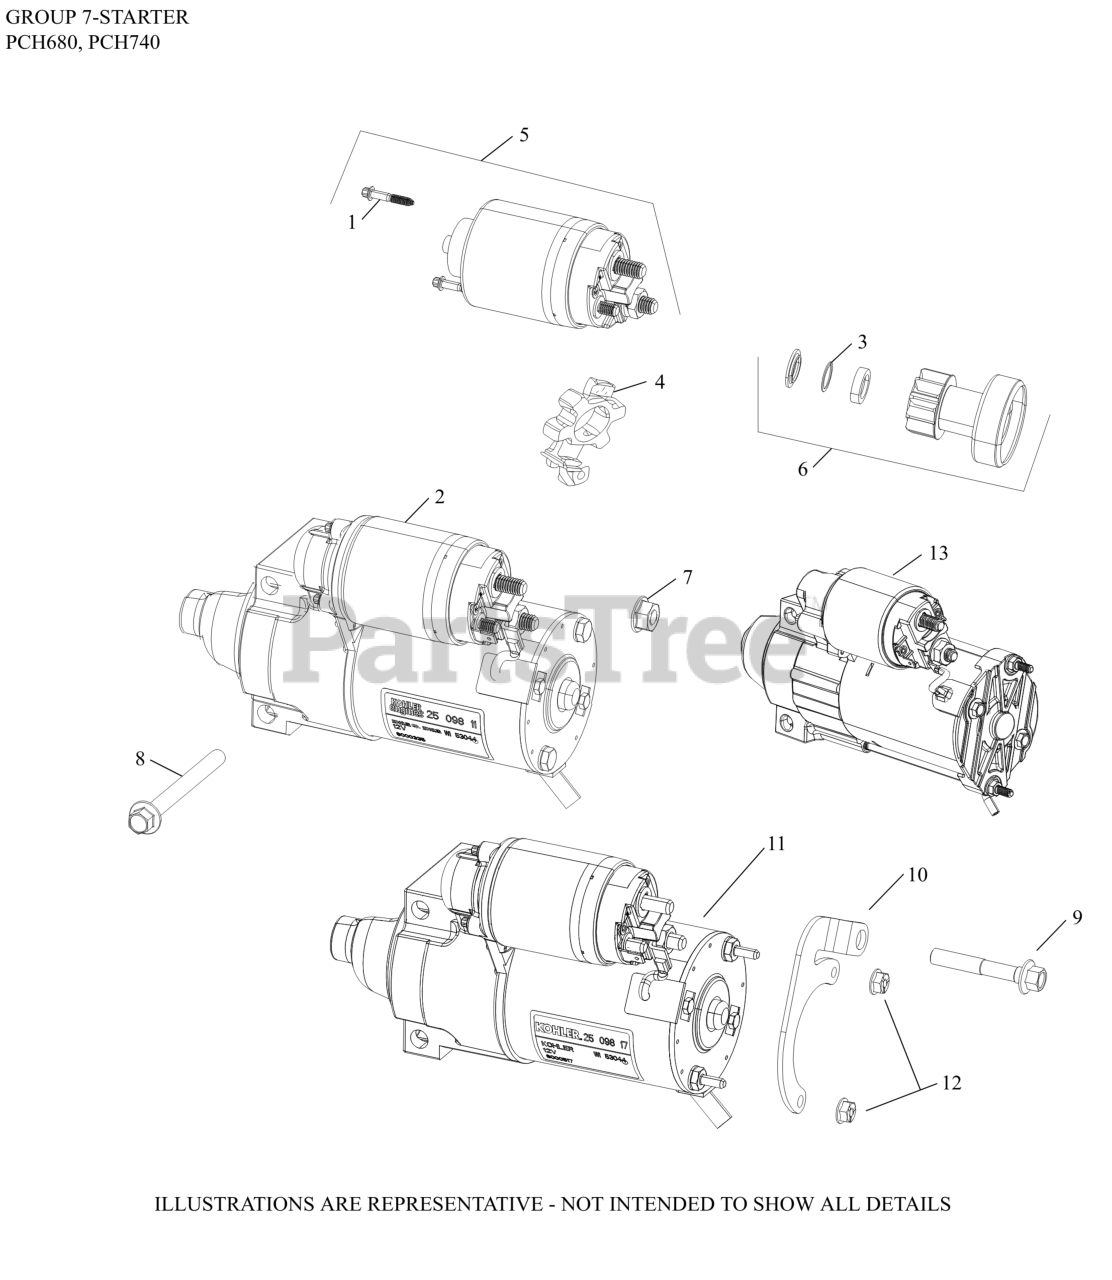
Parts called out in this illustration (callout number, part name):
2	STARTER, SOLENOID SHIFT-(#2509824S)
7	NUT, FLG M8X1.25
8	SCREW, FLG M8X1.25X80
